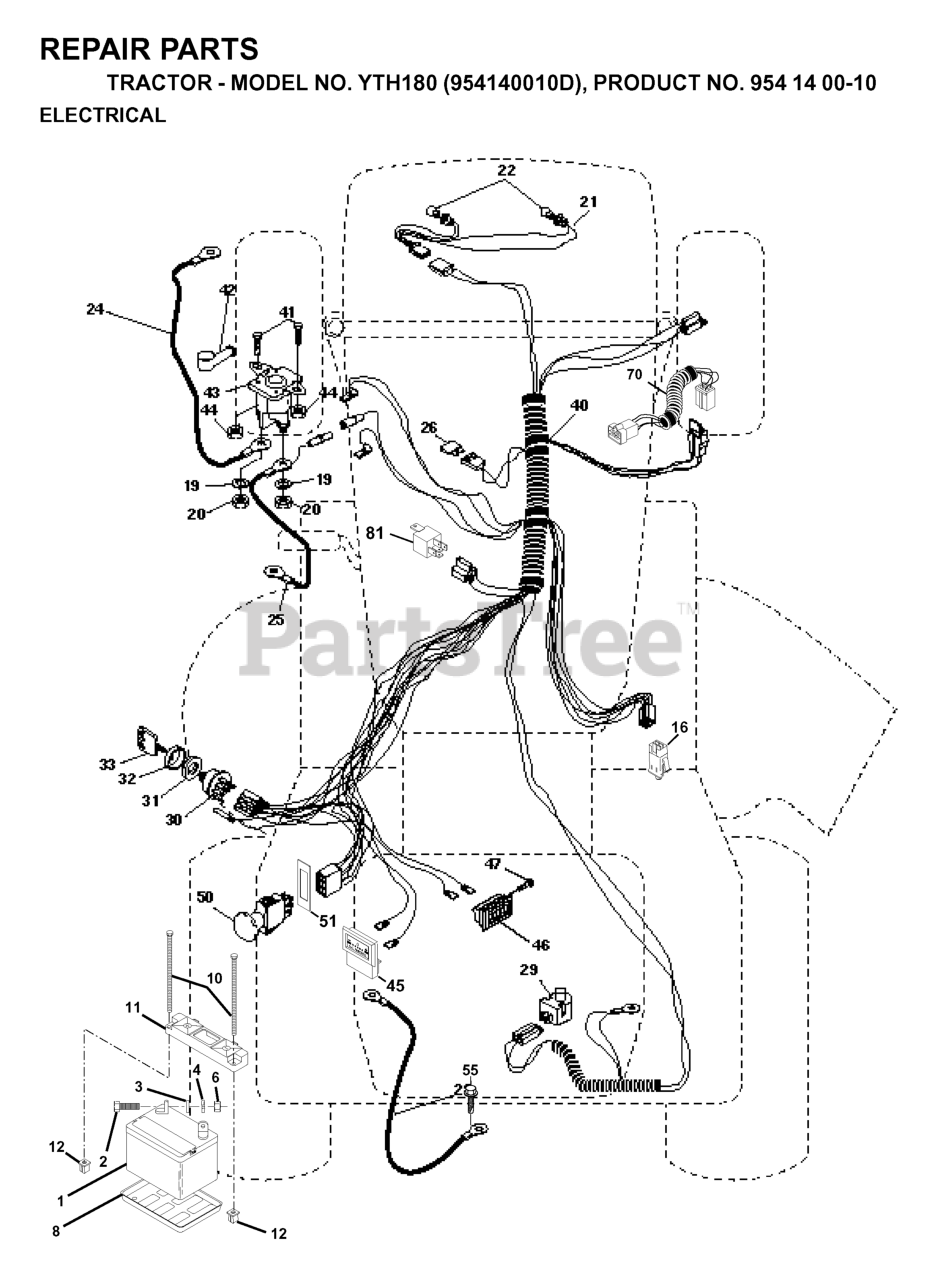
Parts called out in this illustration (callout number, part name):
1	BATTERY 12V .35 AMP
2	BOLT.HEX.1/4.X.3/4.DICHROMATE
4	LOCKWASHER
6	NUT
8	BATTERY TRAY T
10	BOLT 1/4-20 X 7.5
11	BATTERY HOLDDOWN FRONT MOUNT
12	NUT, PUSH NYLON 1/4" BATTERY
16	SWITCH INTERLOCK
19	LOCKWASHER
20	NUT
21	HARNESS LIGHT SOCKET
24	BATTERY CABLE GT
25	CABLE BATTERY 6 GA 22" W/16W
28	CABLE GROUND 6 GA 21" 90T BLK
29	PLUNGER SWITCH (COLOR:OLIVE)
30	SWITCH.IGNITION.4.POSITION
31	NUT IGNITION
32	COVER SWITCH KEY
33	KEY.MOLDED.GENERIC
40	WIRING HARNESS
41	BOLT
42	TERMINAL COVER
43	SOLINOID
44	Nut, Keps Blk Hex 1/4-20 UNC
46	HOUR METER T
47	Screw 10-24 x 1/2 Black
50	SWITCH PTO 3 PDT
51	FRAME RETAINING RING
55	Screw 5/16-18 x 1/2 Hex, Self Tapping 5/16-18 x 1/2
